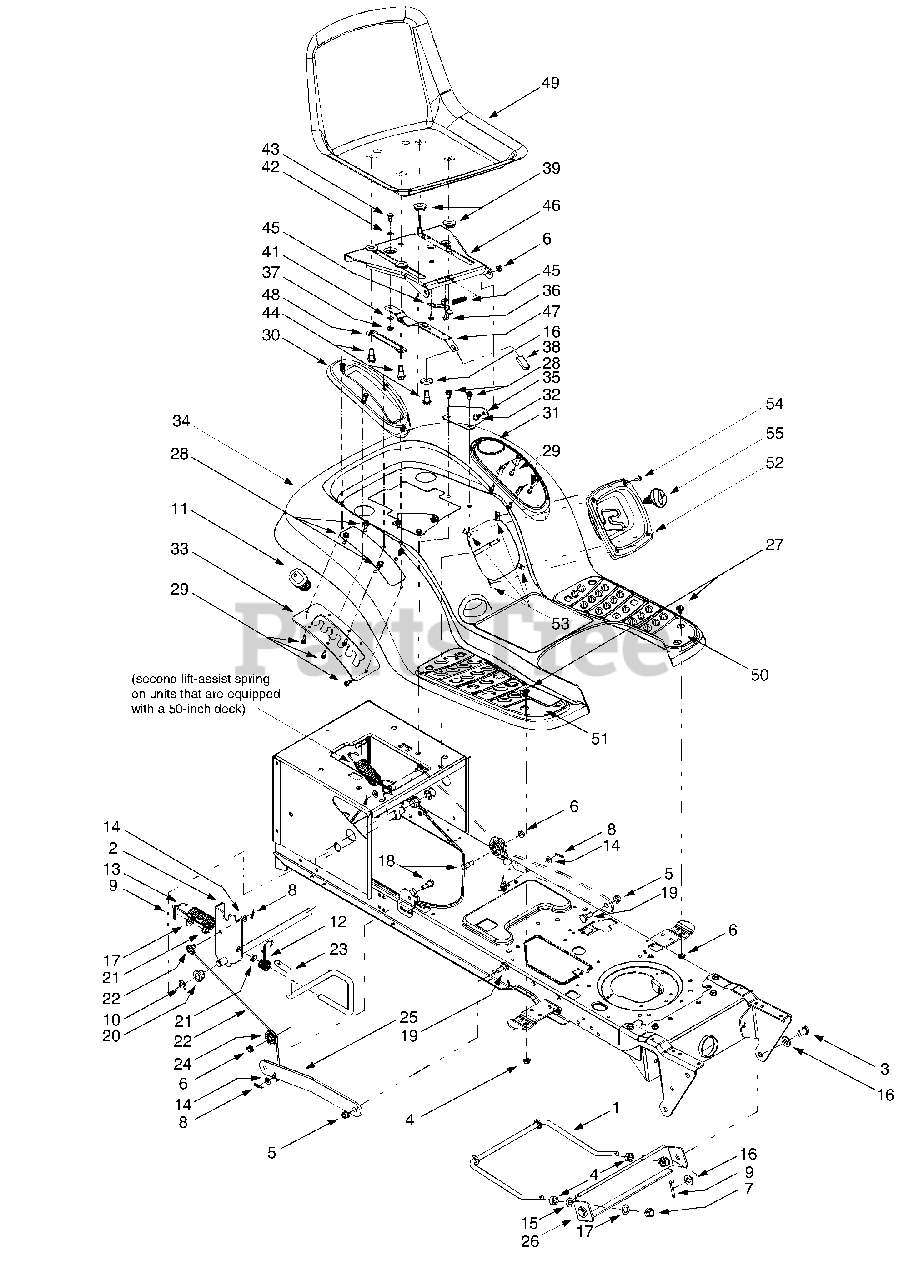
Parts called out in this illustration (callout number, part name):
3	Clevis Pin, .5 x .78
4	Hex Nut, 1/2-13
5	Flange Lock Nut, 3/8-16
6	Flange Lock Nut, 5/16-18
7	Hex Nut, 1/2-13
8	Internal Cotter Pin
9	Cotter Pin
10	E-ring
11	Handle Grip
12	Torsion Spring
13	Lift-assist Spring, 1.15 x 5.99
14	Flat Washer, 5/16
15	Lock Washer, 1/2
16	Flat Washer, .31 x 1.062 x .134
17	Flat Washer, .51 x 1.12 x .06
18	Hex Cap Screw, 5/16-18 x .62
19	Shoulder Screw, .5 x .27, 3/8-16
20	Hex Flange Bearing
21	Snap Flange Bearing
22	Lift Cable, 16.16
23	Lift Handle
24	Roller Pulley
27	Carriage Bolt, 5/16 x .62
28	Self Tapping Screw, 5/16-18 x .625
29	Self Tapping Screw, 1/4-15 x .75
30	Lift Lever Cover
31	Cover w/ Cup Holder
32	Shoulder Screw, .437 x 1.62
36	Screw, #10-16 x .375
37	Hex Flange Lock Nut, 1/4-20
38	Seat Adjuster Grip
39	Spacer
41	Spring Washer, .265 x .562 x .025
42	Flat Washer, .344 x .62 x .03
43	Shoulder Screw, .340 x .285,1/4-20
44	Shoulder Screw, .50 x .50, 3/8-16
45	Seat Stop
48	Seat Adjustment Selector
49	Seat, Radiant Yellow w/ Drain Holes
50	LH Foot Pad
51	RH Foot Pad
52	Shift Cover
53	Speed Nut, 1/4-20
54	Phillips Screw, 1/4-20 x .75
55	Shift Knob
